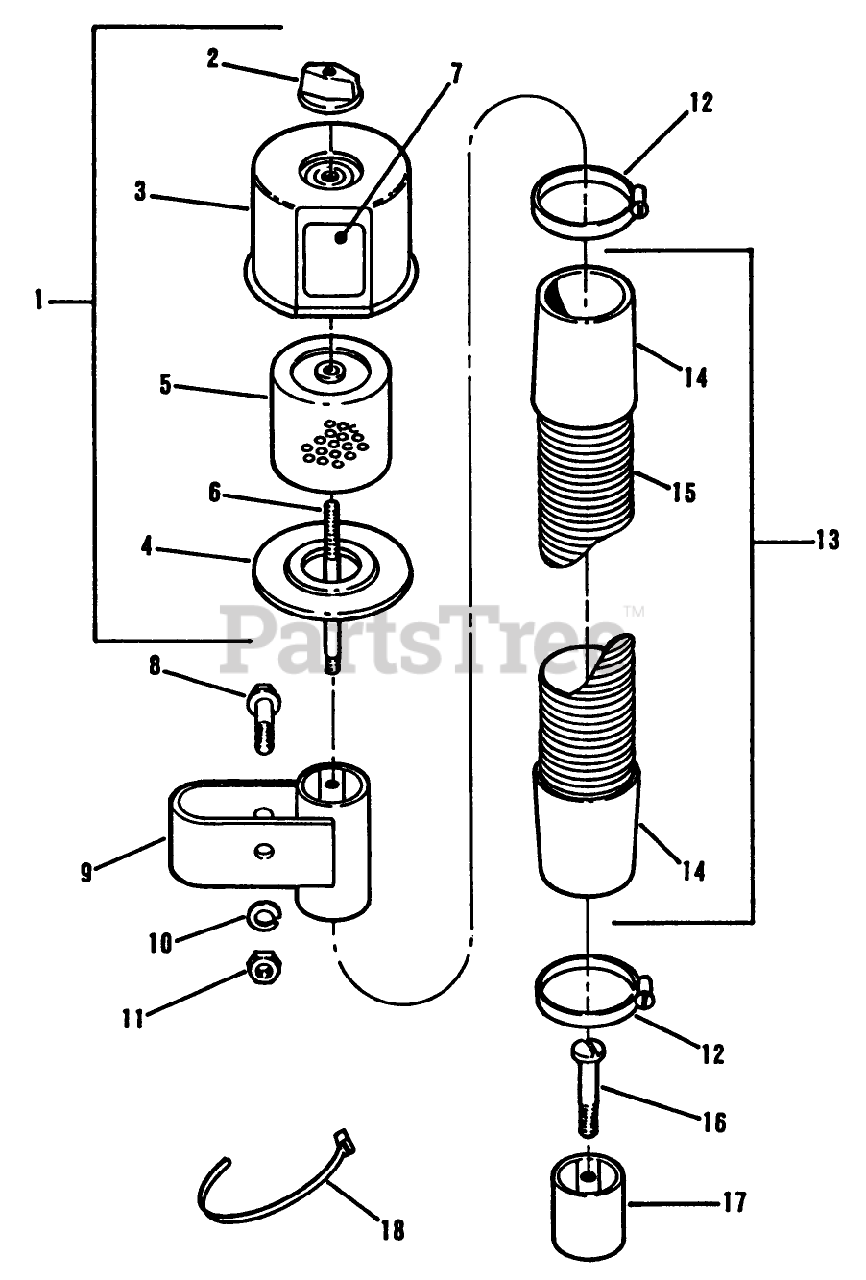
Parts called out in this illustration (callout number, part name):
3	Air Cleaner Cover
4	Air Cleaner Base
5	Air Cleaner Cartridge
6	Stud
7	Decal
10	WASHER
11	NUT
12	CLAMP - HOSE
